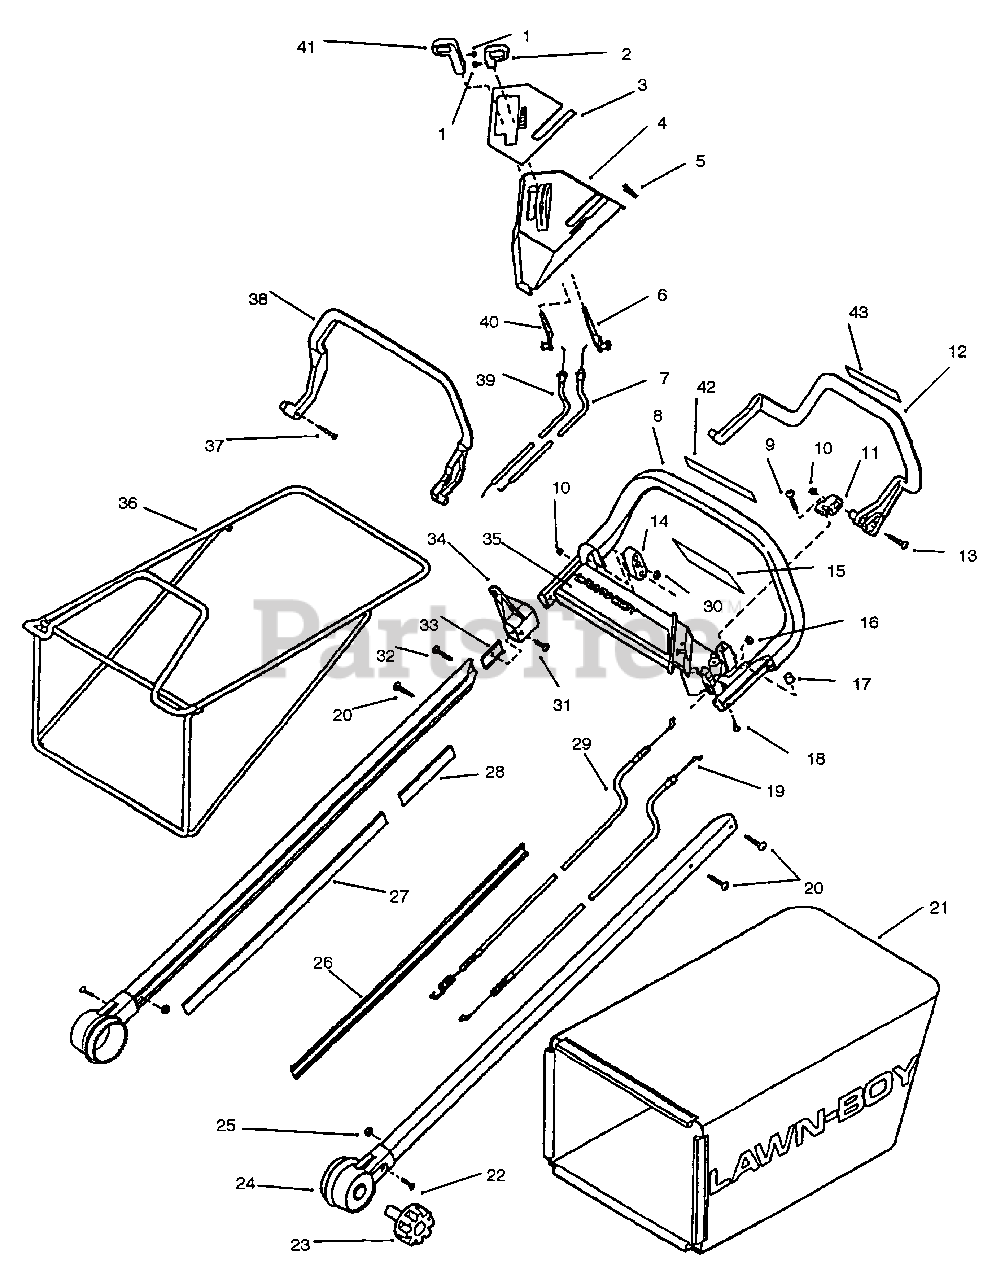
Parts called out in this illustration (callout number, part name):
1	Screw-Set
2	Assembly-Knob, Throttle (Incl. Ref. #1)
4	Assembly-Cover, Upper (Incl. Ref. #3)
6	Lever-Throttle
7	Assembly-Cable, Throttle
8	Assembly-Handle & Decal (Incl. Ref. #20 & 34)
11	Pivot-Bail
12	Bail-Self-propelled
14	Block-Bail
15	Decal-Warning
16	Nut-Cable, Self-propelled
19	Assy.-Cable, Eng. Brake
20	Screw-Thread Forming
23	Knob-Mounting, Handle
24	Assembly-Shaft, Handle (Incl. Ref. # 23 & 25)
26	Insert-Handle, Cable Side
27	Insert-Handle
28	Insert-Handle
29	Assy.-Cable, Self-propelled
33	Plate-Nut
34	Guide-Rope
35	Decal-Lawn-Boy
38	Bail-Brake, Engine
39	Assy.-Cable, Gear Select
40	Lever-Gear, Select
41	Assy.-Knob, Gear Select (Incl. Ref. #1)
42	Decal-Zone Start
43	Decal-Self-Propelled
